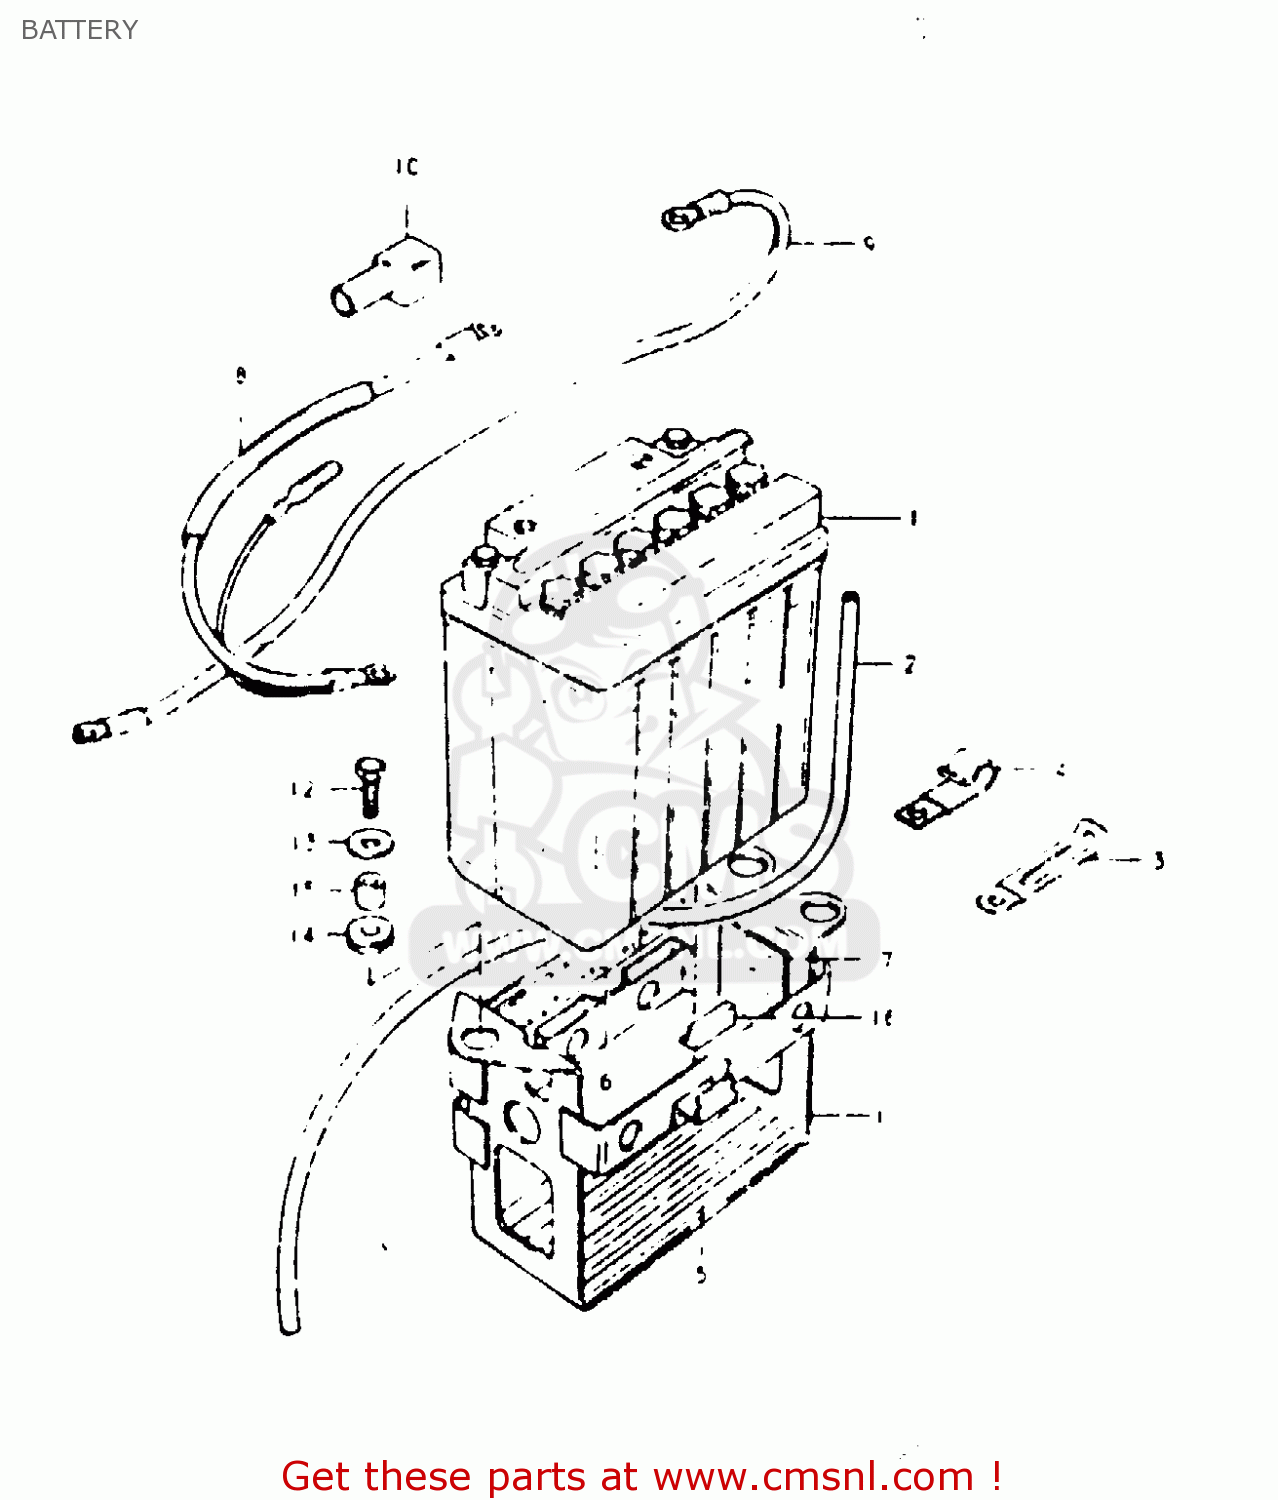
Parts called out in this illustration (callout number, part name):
1	BATTERY ASSY (12V)
2	HOSE,BATTERY EXHAUST
3	CLAMP L:35
4	CLAMP
5	PROTECTOR,BATTERY
6	PROTECTOR(20X90)X4
7	PROTECTOR,BATTERY
8	WIRE,BATTERY PLUS
9	LEAD WIRE,BATTERY(-)
10	CAP,TERMINAL
11	HOLDER,BATTERY
12	BOLT, UPPER
13	WASHER
14	CUSHION
15	SPACER(6.1X9X7.5)
16	CUSHION,FRAME COVER
